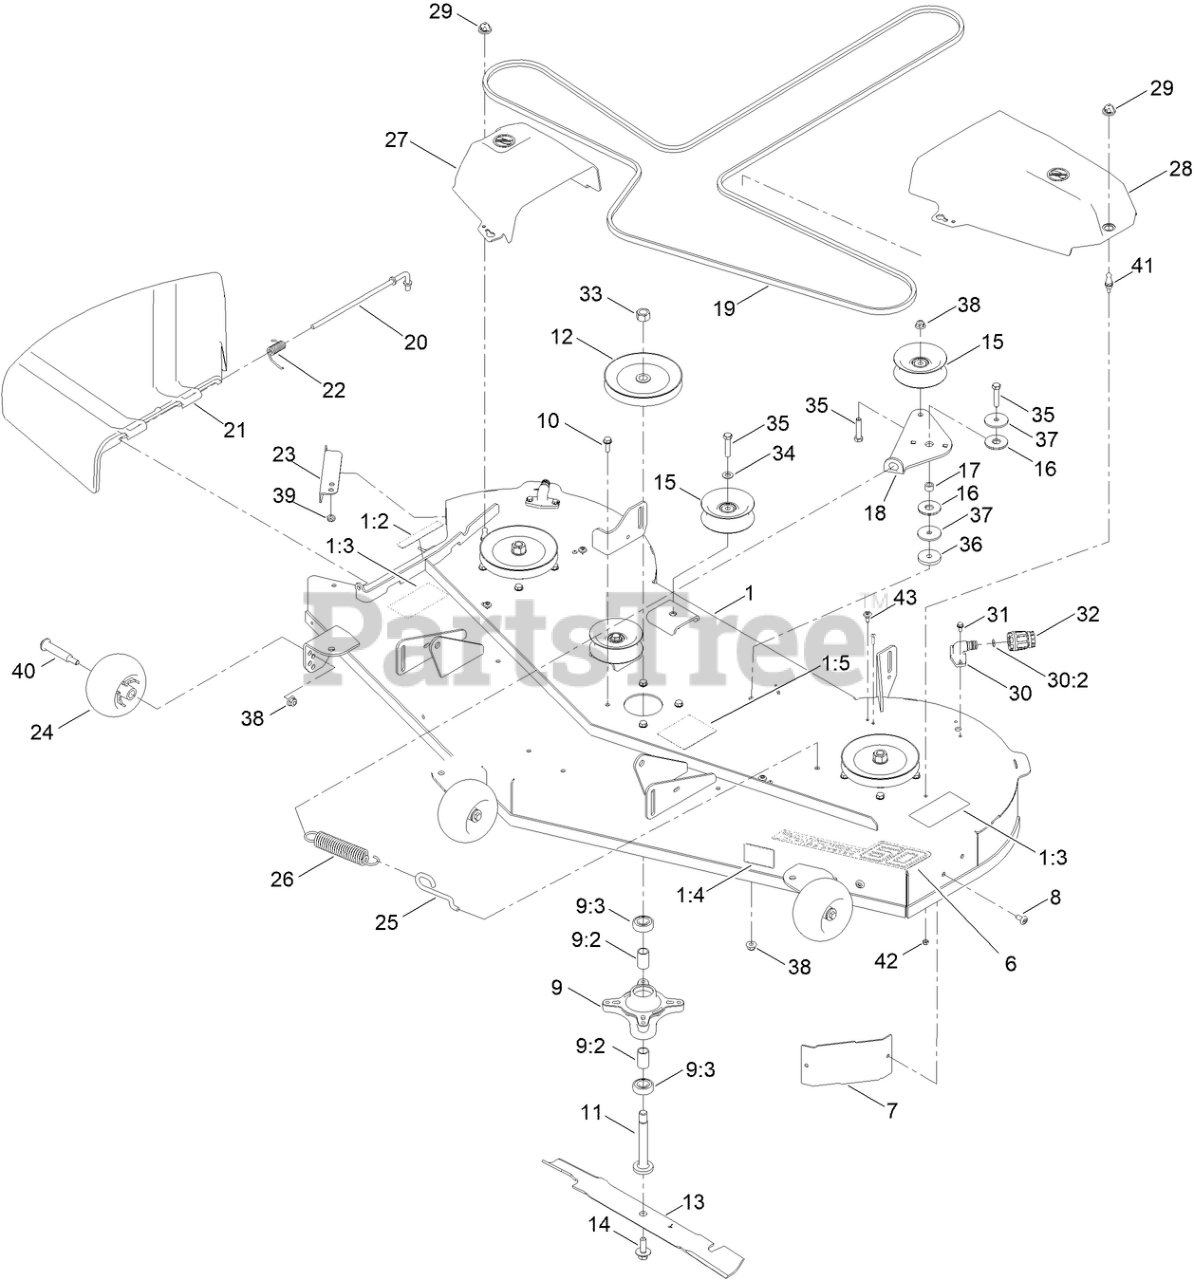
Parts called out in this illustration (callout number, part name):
1	60 IN DECK DECAL ASM
1:2	DECAL-DANGER DEFLECTOR [BLK-TXT]
1:3	DECAL-DANGER, DECK
1:4	DECAL-SCALP, ANTI
1:5	DECAL-ROUTING, BELT
6	DECAL - IRON FORGED 60
7	BAFFLE-CORNER
9	SPINDLE ASM
9:2	SPACER
9:3	BEARING-BALL
10	SCREW-TAPTITE
11	SHAFT-SPINDLE
12	PULLEY
13	BLADE-HI FLOW, 20.5 INCH
14	BOLT-BLADE, SEMS
15	PULLEY-IDLER, FLAT
16	WASHER-FRICTION, COMPOSITE
17	SPACER
18	ARM-IDLER
19	BELT-V (A SEC, 154.96 EL)
20	ROD-PIVOT
21	DEFLECTOR-DISCHARGE
22	SPRING-TORSION
23	BAFFLE-CUTOFF
24	ROLLER-SCALP, ANTI
25	HOOK-RETURN SPRING
26	SPRING-EXTENSION
27	COVER-BELT, RH
28	COVER-BELT, LH
29	GROMMET-BALL
30	FITTING-WASHOUT
30:2	O-RING
31	SCREW-HWH
32	CONNECTOR-HOSE
33	NUT-HEX
34	WASHER-FLAT
35	SCREW-HH
36	WASHER-PLAIN
37	WASHER-REBOUND
38	NUT-HF, NI
40	BOLT-SHOULDER
41	STUD-BALL
42	NUT-LOCK
43	SCREW-SHOULDER
